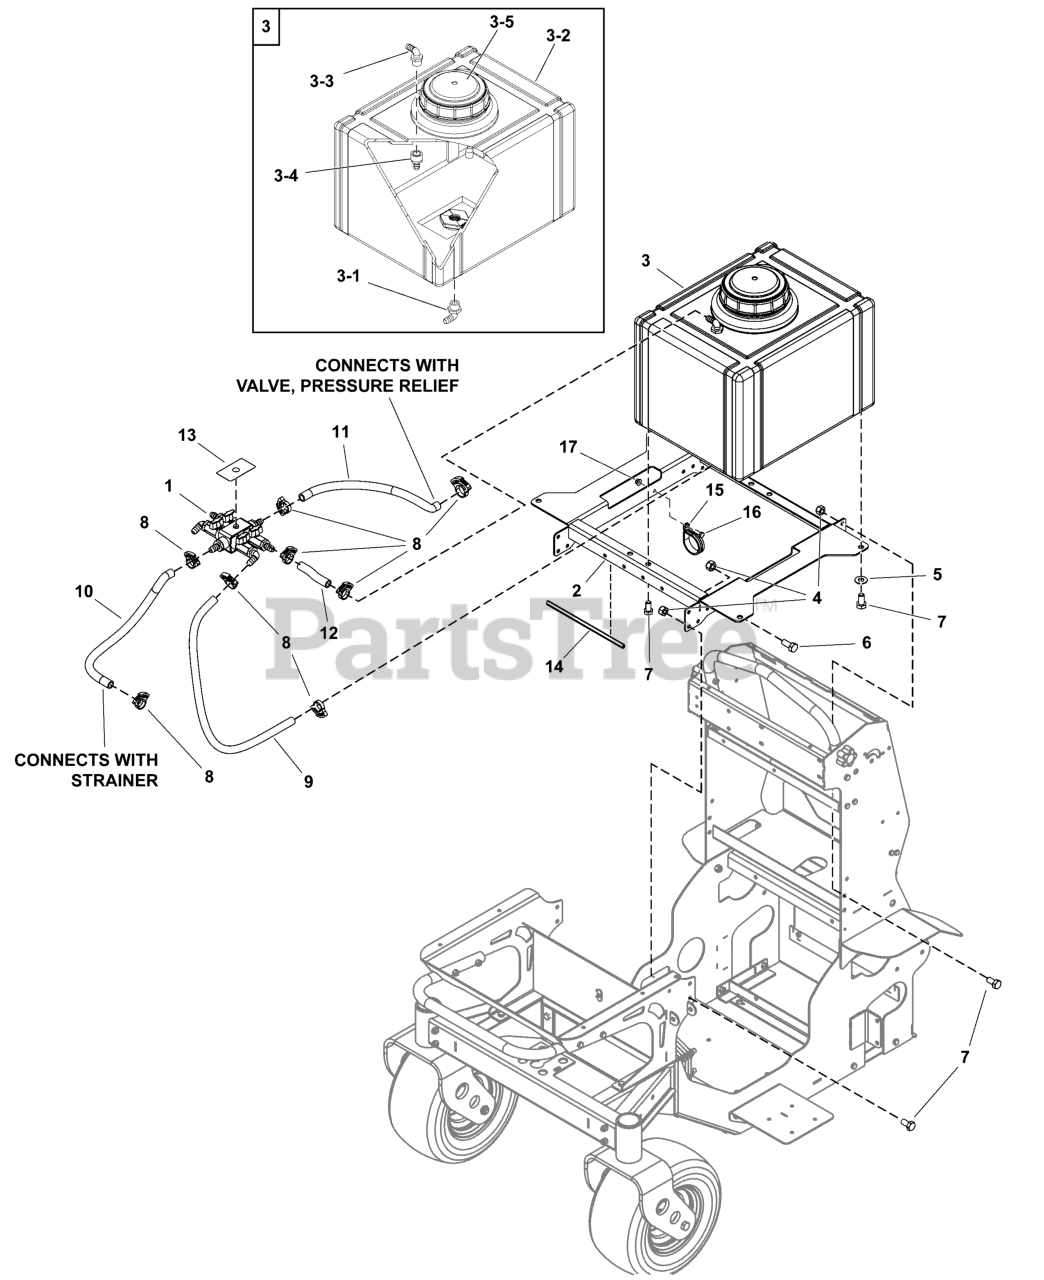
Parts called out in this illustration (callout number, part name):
1	Refer to: Spray Tank Valve Group
2	WELD, SPRAY TANK MOUNT
3	ASM, SPRAY TANK
3-1	FITTING, 3/4 MPT - 1/2 BARB, 90 ELBOW
3-2	TANK, 12 GAL RT W/SUMP HDPE NAT
3-3	FITTING, 1/2 MPT - 1/2 BARB, 90 ELBOW
3-4	FITTING, 1/2 FPT - 1/2 BARB
3-5	LID, TANK, SPRAY (G0134)
4	NUT-HEX-NYLK, 0.3125"-18 SS188
5	WSHR-STL, FLT .343" X .750" X .050" SPC SS188
6	SCR-CAP, HEX .3125"-18 X .750" SS188
7	SCR-CAP, HEX .3125"-18 X .625" SS188
8	SNAP GRIP CLAMP .656 - .750 ID
9	HOSE, TANK SUPPLY, 0.5" ID, 28" LONG
10	HOSE, FILTER SUPPLY, 0.5" ID, 25" LONG
11	HOSE, MANIFOLD SUPPLY, 0.5" ID, 14" LONG
12	HOSE, TANK RETURN, 0.5" ID, 2" LONG
13	DECAL, SPRAY TANK SUCTION / RETURN LABEL
14	TRIM FOR CONSOLE, 7 INCH
15	CLAMP, HARNESS ROUTING, SS
16	SCR-CAP, HEX .250"-20 X .750" SS188
17	NUT-HEX-NYLK, FLG .250"-20 SS188
